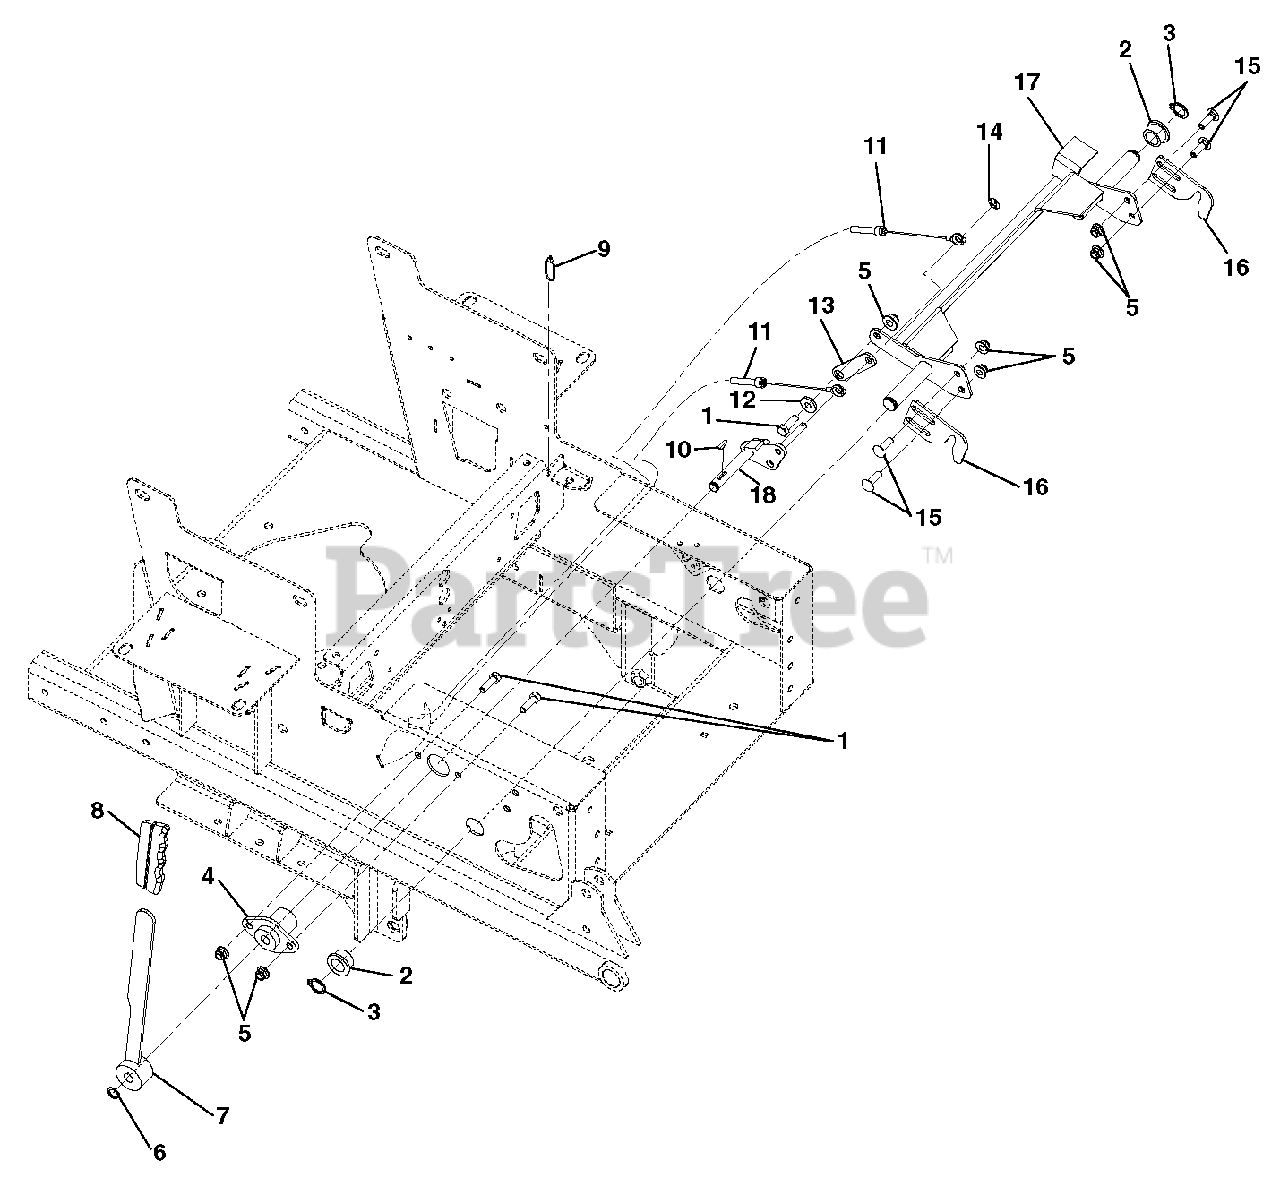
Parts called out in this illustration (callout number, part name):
1	Bolt, Hex .31-18 x 1.00 Grade 5
2	Bushing, Flange .750 x 1.000 x .625 x 1.250
3	Ring, Retaining-External .689 x .077
4	Bushing, Flanged
5	Nut, .31-18 Nyloc Flange
6	Ring, Retaining-External .500 x .050
7	Weldment, Parking Brake Arm
8	Grip, Parking Brake
9	Cable Tie
10	Key, Woodruff .13 x .63 HRD#5
11	Cable, Brake Actuating
12	Bushing, Flange .325 x .499 x .26 x .88
13	Plate, Neutral Interlock
14	Nut, Push .312
15	Bolt, Round Head Square Neck .31-18 x 1.00 Grade 5
16	Neutral Lock Latch
17	Weldment, 100I Neutral Lock
18	Weldment, Park Brake Arm
